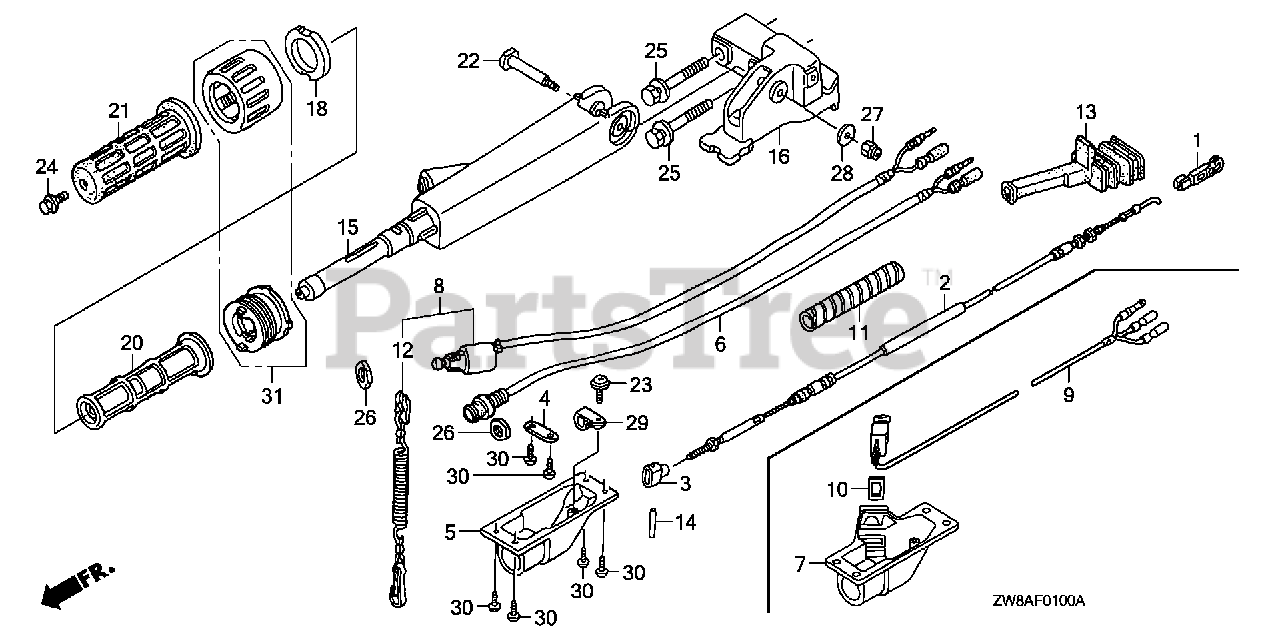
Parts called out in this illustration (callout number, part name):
1	LINKAGE, PIVOT
2	CABLE, THROTTLE
3	PIVOT, THROTTLE CABLE
4	PLATE, SHIFT
6	SWITCH ASSY., STARTER
7	COVER, SWITCH (PT)
8	SWITCH ASSY., EMERGENCY STOP
9	SWITCH ASSY., POWER TILT
10	STAY, POWER TILT SWITCH
11	TUBE, SPIRAL B
12	WIRE, EMERGENCY
13	GROMMET, OIL CASE (A)
14	PIN, THROTTLE CABLE
15	HANDLEBAR *NH246* (LOOSY GRAY)
16	BRACKET, HANDLEBAR *NH246* (LOOSY GRAY)
17	GRIP ASSY., THROTTLE FRICTION
18	PAD, THROTTLE FRICTION
19	BLOCK, THROTTLE FRICTION
20	PIPE, GRIP
21	RUBBER, GRIP
22	SCREW, HANDLE PIVOT
23	SCREW, TAPPING (4X10)
24	BOLT, FLANGE (6X12)
25	BOLT-WASHER (10X55)
26	NUT, HEX. (16MM)
27	NUT, SELF-LOCK (8MM)
28	WASHER (8MM)
29	CLIP, WIRE HARNESS (6.3MM)
30	SCREW, TAPPING (4X12)
31	GRIP ASSY., THROTTLE FRICTION
